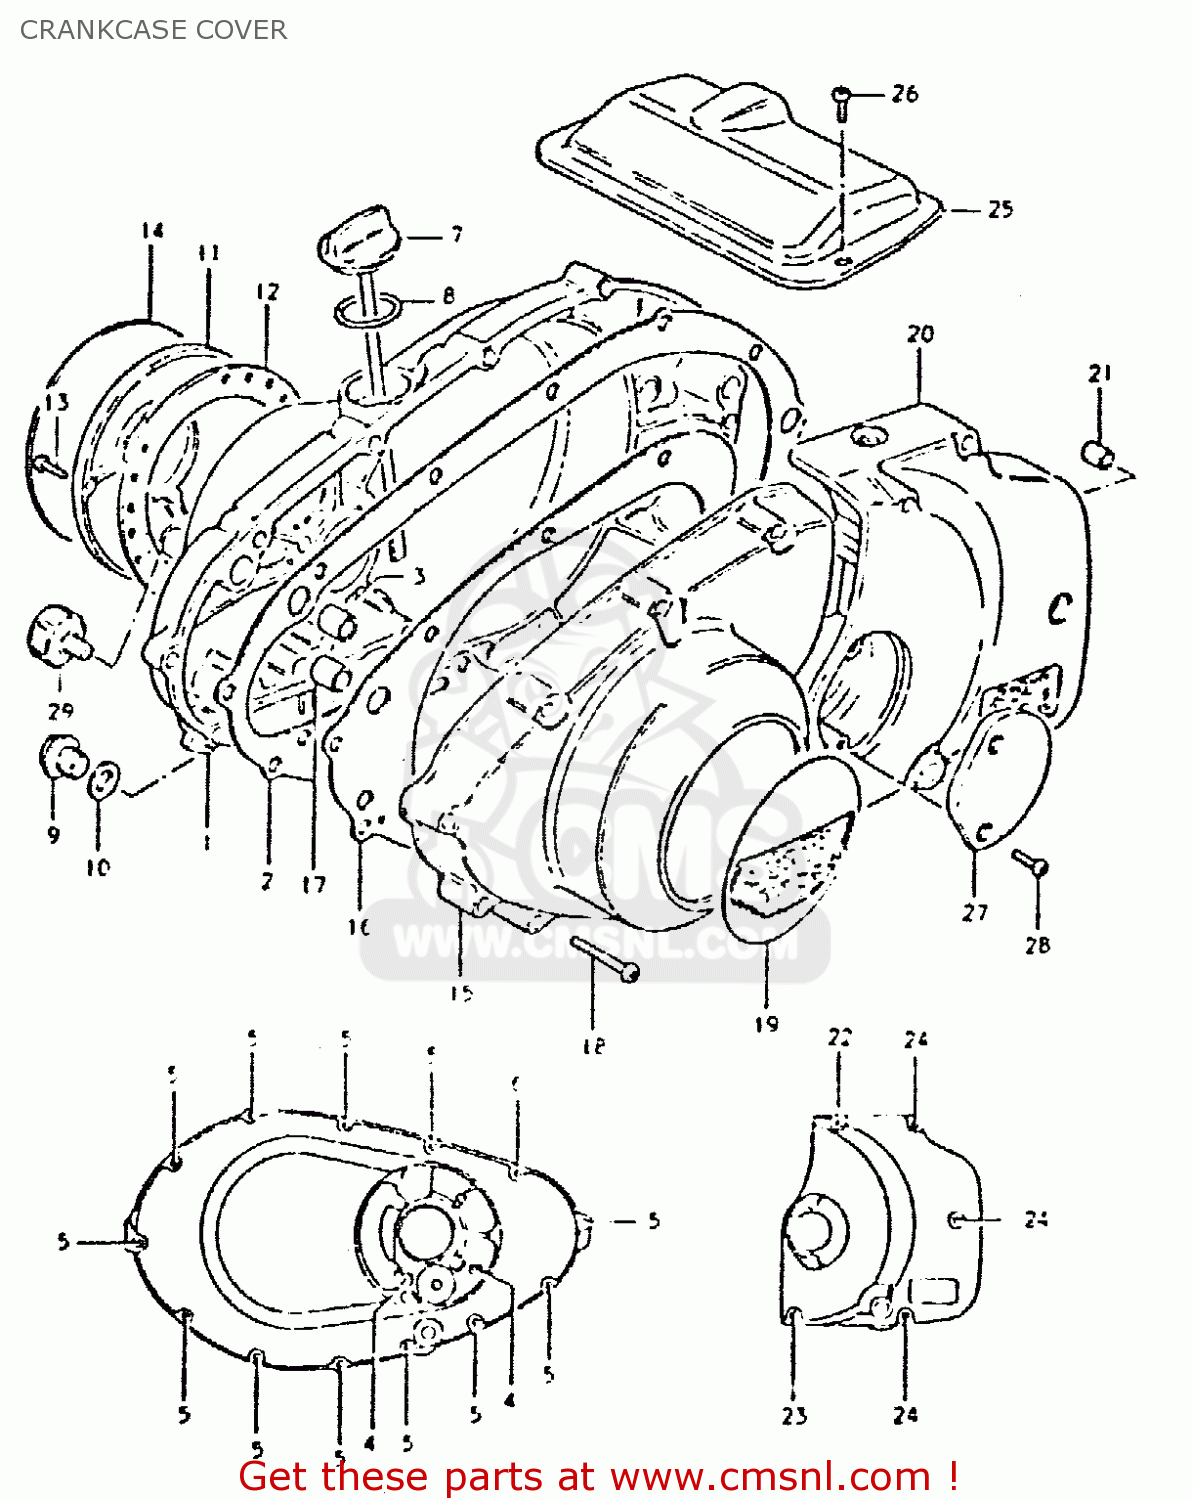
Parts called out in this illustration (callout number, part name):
1	COVER,CLUTCH
2	GASKET,CLUTCH COVER (MCA)
3	PIN
4	SCREW
5	SCREW (6X35)
6	SCREW
7	GAUGE,OIL LEVEL
8	O-RING
9	PLUG (14X12)
10	GASKET(14X19.2X2) (NAS)
11	COVER,CONTACT BREAKER
12	GASKET,CONTACT BREAKER COVER (NAS)
13	SCREW
14	EMBLEM
15	COVER
16	GASKET,MAGNETO COVER (MCA)
17	PIN
18	SCREW (6X35)
19	EMBLEM
20	COVER,SPROCKET
21	PIN
22	SCREW 6X65
23	SCREW
24	SCREW
25	COVER,STARTER MOTOR
26	SCREW
27	CAP,CLUTCH RELEASE ADJUST
28	SCREW 5X12
29	SWITCH ASSEMBLY
